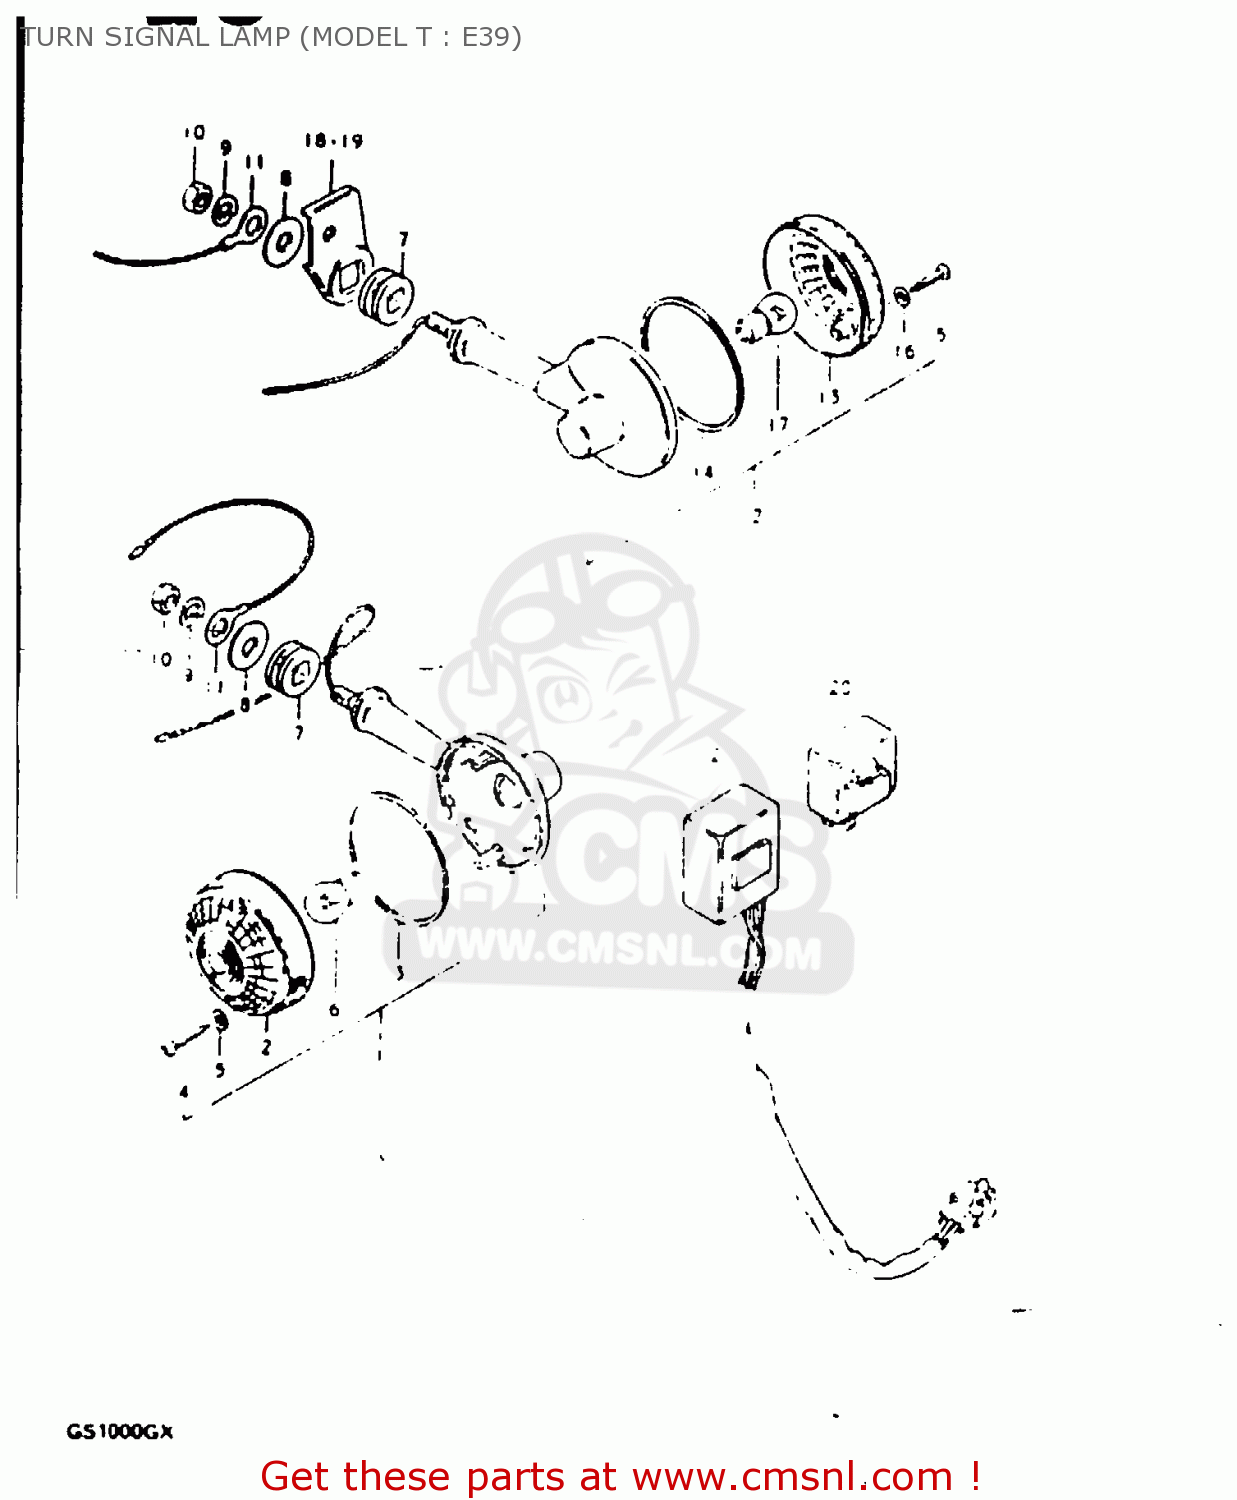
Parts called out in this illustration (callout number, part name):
1	LAMP, REAR TURN SIGNAL
2	LENS
3	GASKET (NAS)
4	SCREW (4X30)
5	GASKET (NAS)
6	BULB(12V21W)
7	CUSHION
8	WASHER (10.5X30X2.3)
9	LOCK WASHER
10	NUT
11	LEAD WIRE,EARTH
12	LAMP, REAR TURN SIGNAL
13	LENS
14	GASKET (NAS)
15	SCREW (4X30)
16	GASKET (NAS)
17	BULB(12V21W)
18	BRACKET,RR TURNSIGNAL LAMP,R
19	BRACKET,RR TURNSIGNAL LAMP,L
20	RELAY ASSY,TURNSIGNAL
21	UNIT,TURN SIGNAL CONTROL
